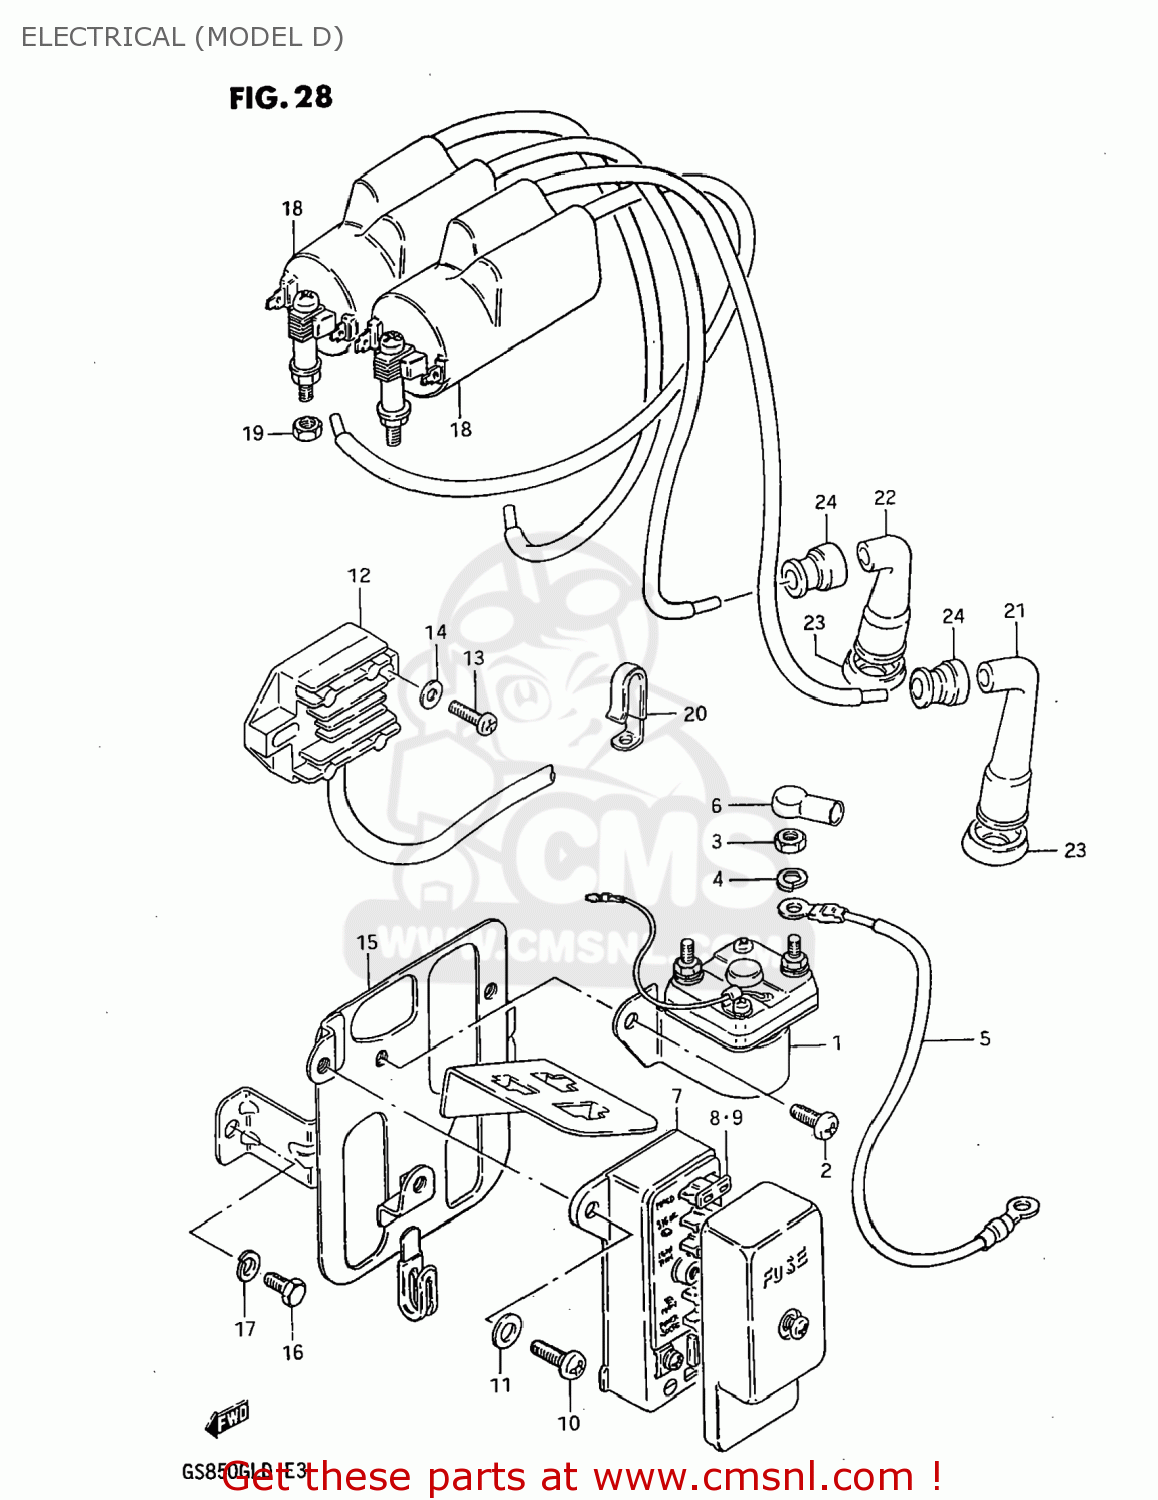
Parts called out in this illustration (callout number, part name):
1	RELAY ASSY,STARTING MOTOR
2	SCREW
3	NUT 6MM
4	LOCK WASHER
5	CABLE,STARTING MOTOR
6	CAP,STARTER RELAY
7	BOX ASSEMBLY,FUSE
8	FUSE(10A)
9	FUSE(15A)
10	SCREW 6X12
11	WASHER
12	RECTIFIER ASSEMBLY
13	SCREW
14	WASHER
15	HOLDER COMP,ELECTRONIC PARTS
16	BOLT
17	LOCK WASHER
18	COIL ASSEMBLY,IGNITION
19	NUT
20	CLAMP
21	CAP ASSY,SPARK PLUG
22	CAP,SPARK PLUG
23	SEAL,SPARK PLUG
24	SEAL,SPARK PLU
